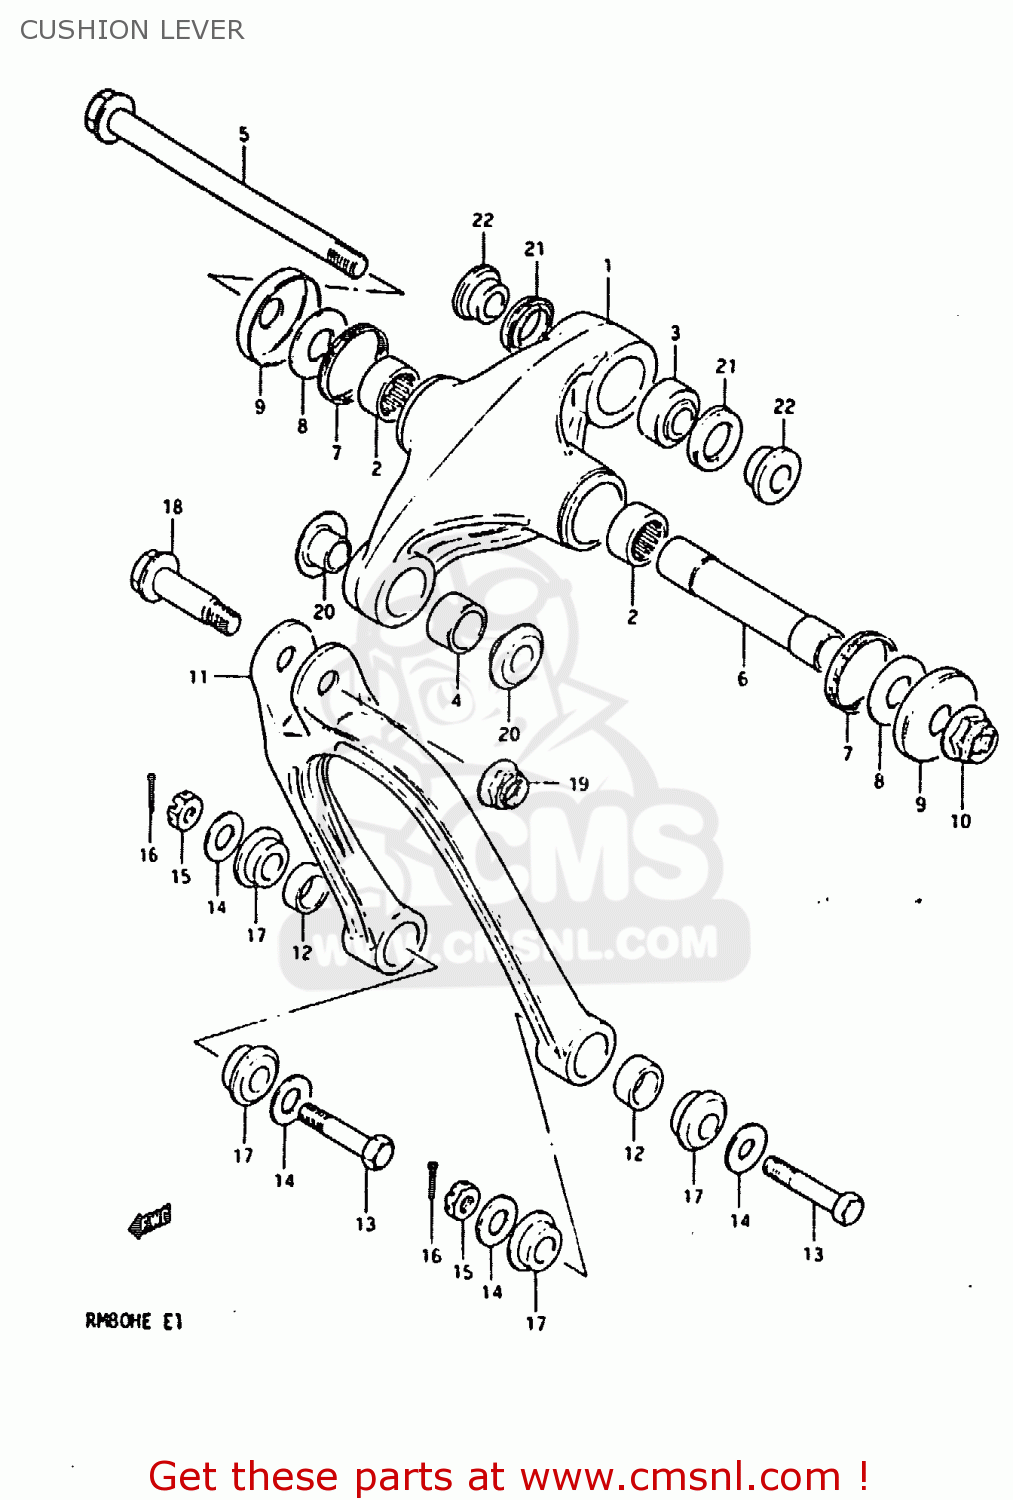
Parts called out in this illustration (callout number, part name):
1	LEVER SET,REAR CUSHION
2	BEARING(17X25X20)
3	BEARING
4	BUSH,FR
5	SHAFT,REAR CUSHION LEVER
6	SPACER,REAR CUSHION LEVER
7	DUST SEAL,RR CUSHION LEVER
8	WASHER
9	DUST COVER,REAR CUSHION
10	NUT 12MM
11	ROD, CUSHION LEVER
12	BUSHING
13	BOLT,REAR CUSHION LEVER
14	WASHER
15	NUT 8MM
16	PIN 20X20
17	SPACER,REAR CUSHION ROD
18	BOLT(10X44)
19	NUT
20	SPACER,REAR CUSHION,FRONT
21	DUST SEAL,REAR CUSHION,LEFT
22	SPACER
